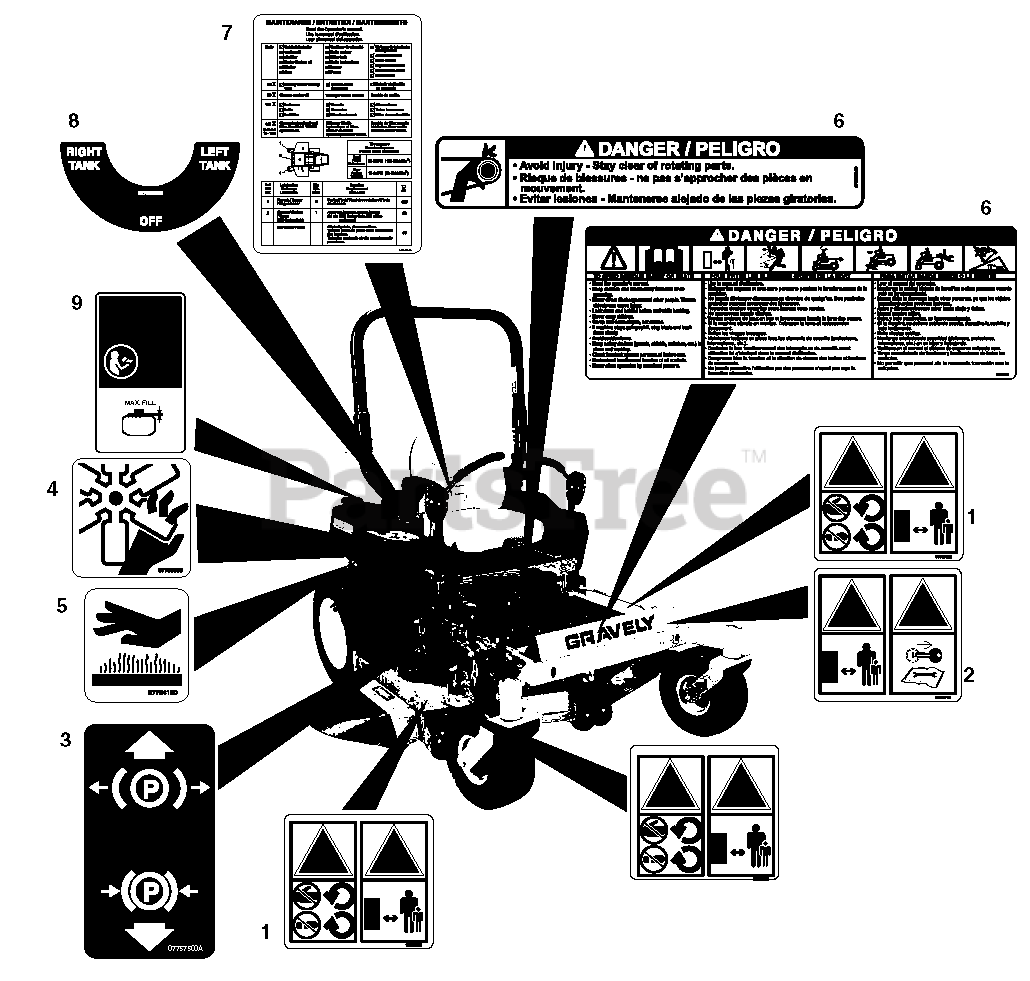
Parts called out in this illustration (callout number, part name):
1	Decal, CE Deck
2	Decal, CE Caution
3	Decal, Parking Brake Lever
4	Decal, Danger Fan
5	Decal, Hot Surface
6	Decal, Common Danger/Fuel
7	Decal, Maintenance Instructions
8	Decal, Fuel Control Valve
9	Decal, Fuel Warning
